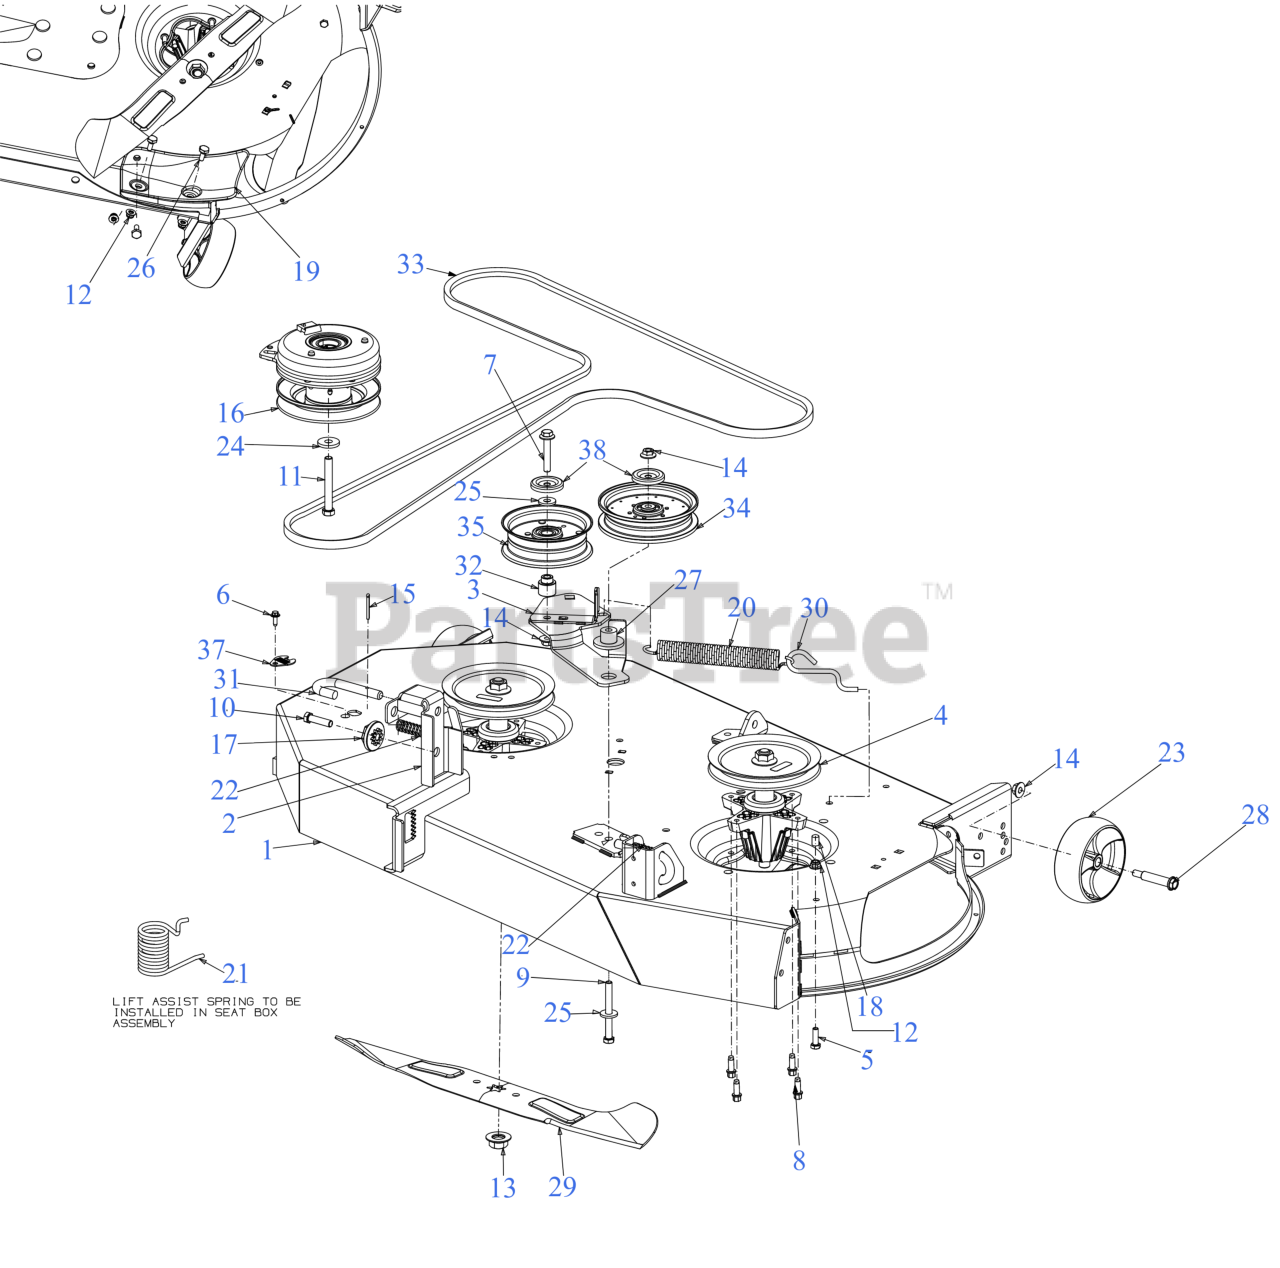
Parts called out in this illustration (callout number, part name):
3	BRACKET ASSEMBLY-DECK IDLER
4	SPINDLE ASSEMBLY
5	SCREW 5/16-18 x 1.0 GR5
6	SCREW M6-1 x .625
7	SCREW 3/8-16 x 2.25 GR5
8	SCREW 5/16-18 x .875
9	SCREW 3/8-16 x 3.50 GR5
10	SCREW 3/8-16X1.5 GR5
11	SCREW 7/16-20 x 3.25 GR5
12	FLANGE LOCK NUT 5/16-18
14	FLANGE LOCK NUT
15	COTTER PIN-5/32 DIA
16	ELECTRIC PTO CLUTCH
17	DECK ADJUSTMENT GEAR
19	DISCHARGE BAFFLE
20	EXTENSION SPRING
21	TORSION SPRING
22	COMPRESSION SPRING .66 OD x 1
23	DECK WHEEL (5.0 DIA x 1.875)
24	FLAT WASHER .445 x 1.248 x .170
25	FLAT WASHER .406ID X1.0 OD
26	SHOULDER SCREW
27	DOUBLE SHOULDER SPACER
28	SHOULDER BOLT (.50 X 2.0 x 3/8 -16)
29	23.25" BLADE (HIGH LIFT)
29	Cub Cadet 46" BLADE SET
29	Genuine Factory Parts 46" HI LIFT BLADE SET
30	DECK SPRING HOOK
31	DECK RELEASE PIN
32	SHOULDER SPACER
33	V-BELT A SEC x 125
33	Cub Cadet 46"RZT-L DECK BELT (04325)
33	Troy-Bilt 46" DECK BELT
34	FLAT IDLER PULLEY
35	IDLER PULLEY 4.50" DIA
37	DECK WASH PLUG
38	IDLER PULLEY CAP
